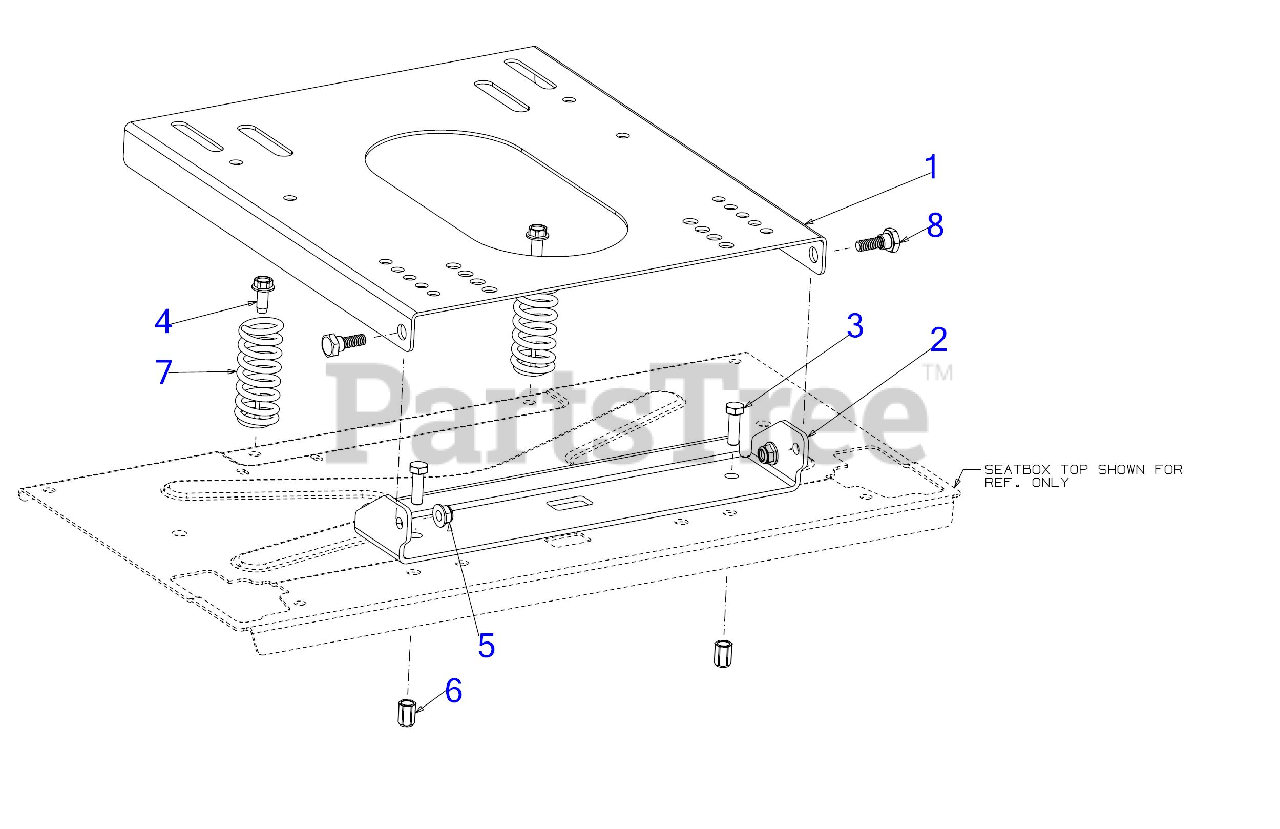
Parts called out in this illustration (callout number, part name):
3	SCREW 5/16-18 x 1.00 GR5
4	SCREW 5/16-18 x .750
5	FLANGE LOCK NUT 5/16-18
6	NUT RIVET 5/16-18
7	COMPRESSION SPRING
8	SHOULDER SCREW .437
